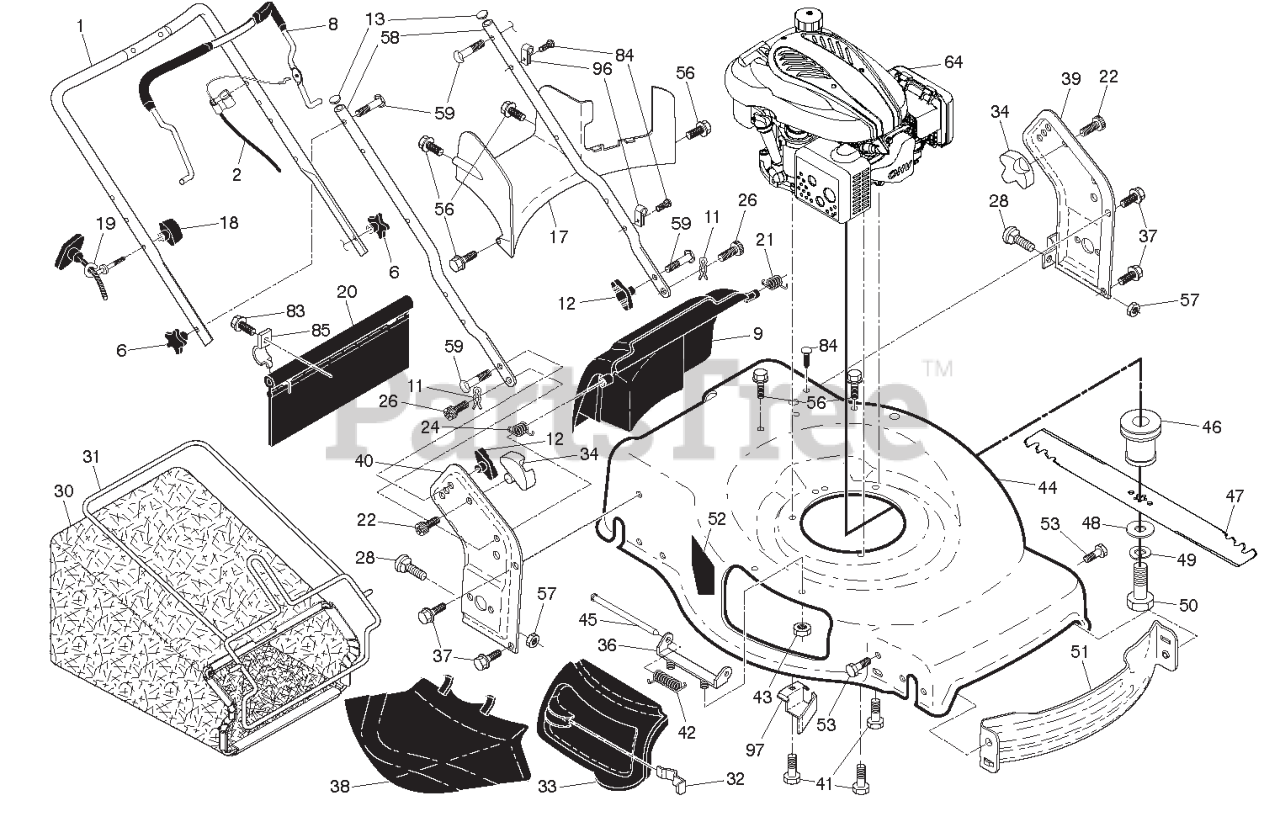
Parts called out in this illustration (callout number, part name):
1	UPPER HANDLE ASSEMBLY
2	CABLE, ENGINE ZONE CONTROL
6	Handle Knob
8	CONTROL BAR
9	REAR DOOR ASSEMBLY
11	HAIRPIN, DOOR/HANDLE PIVOT
12	HANDLE KNOB, STANDARD
13	PLUG, HANDLE BAR
17	REAR BAFFLE
19	ROPE GUIDE
20	REAR SKIRT
21	SPRING, REAR DOOR, LH, BLACK
22	SCREW, PANHEAD, TORX #20
24	SPRING, REAR DOOR, RH, GREY
26	SCREW, REAR DOOR/HANDLE PIVOT
28	BOLT, CARRIAGE
30	GRASSBAG
31	FRAME, GRASSBAG
33	MULCHER DOOR
34	BRACKET, GRASSBAG
36	HING, BRACKET ASSEMBLY
37	BOLT.5/16-18HEX.WHS.HD.LCKSERR
38	DISCHARGE DEFLECTOR
39	HANDLE BRACKET, LH
40	HANDLE BRACKET, RH
41	Screw, Hex Head, Threaded, Rol
42	Spring, Torsion
43	LOCKNUT, HEX 1/4-20
44	KIT, LAWN MOWER HOUSING
45	Rod, Hinge
46	BLADE ADAPTOR
48	Hardened Washer
49	Helical Lockwasher
50	Screw, Hex Head, Grade 8 3/8-2
51	FRONT BAFFLE
52	DECAL, WARNING
53	BOLT.5/16-18HEX.WHS.HD.LCKSERR
56	Screw, Rear Baffle
57	NUT, HEX
58	BAR, LOWER HANDLE
59	Handle Bolt
64	ENGINE,LNCN T322002896-2131008
84	FASTENER, PUSH
85	MOUNTING BRACKET, REAR SKIRT
96	Clip, Cable
97	BELT KEEPER
